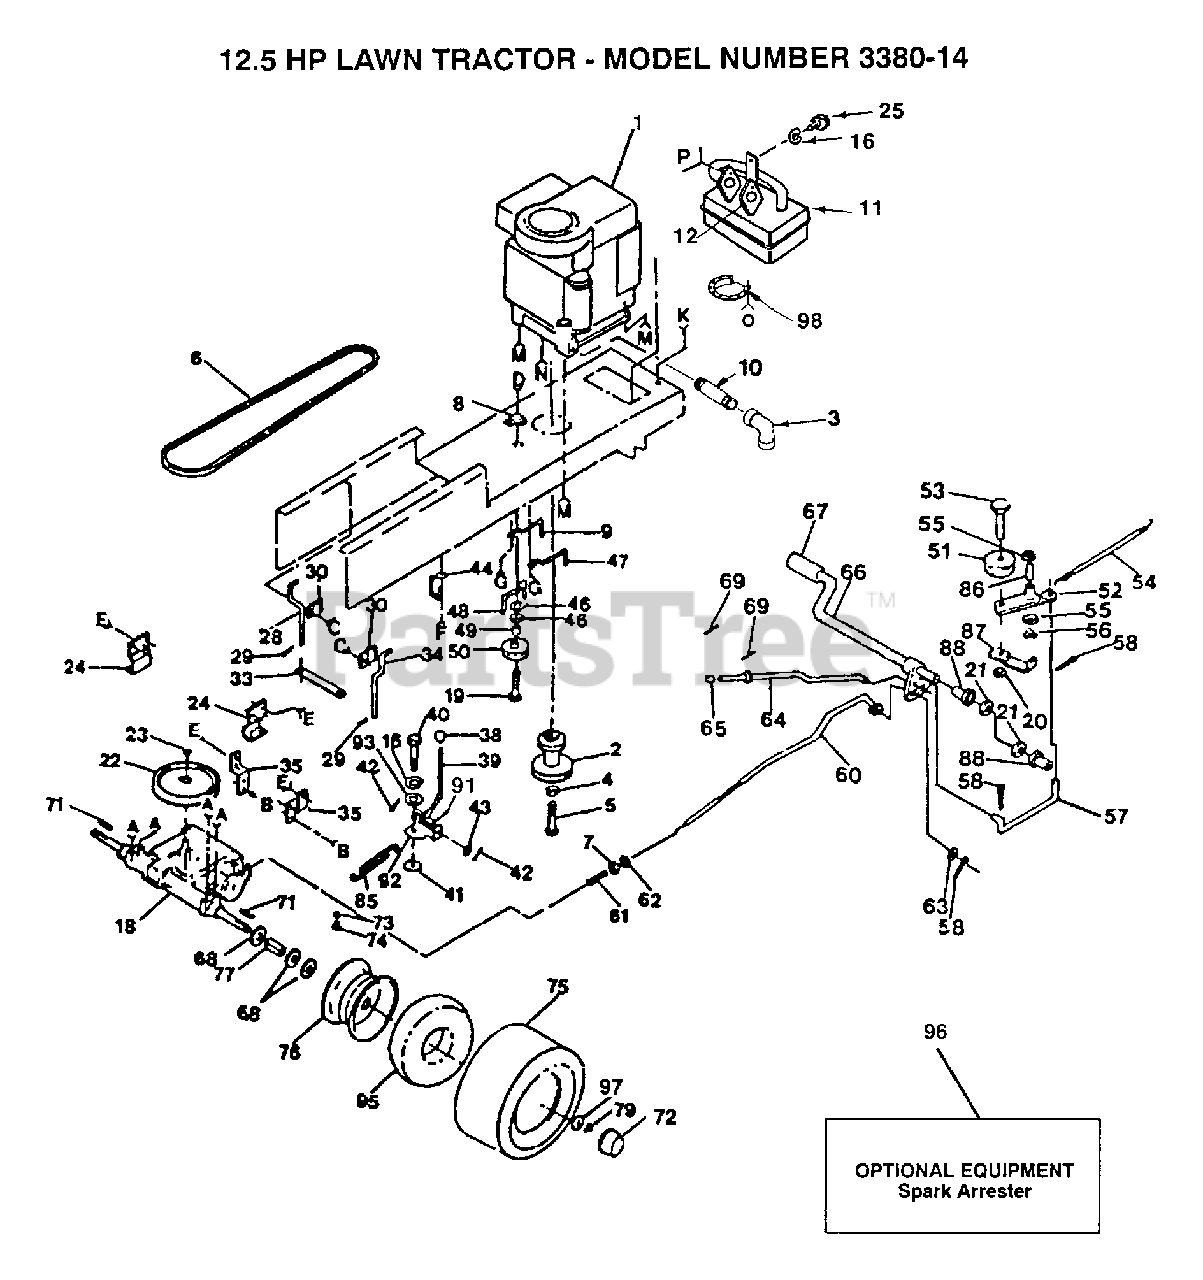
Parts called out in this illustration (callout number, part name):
3	ELBOW
4	LOCKWASHER
5	BOLT
6	BELT-V.90.0.GD.DR
7	NUT
8	CLIP T
9	KEEPER BELT ENGLH
10	PIPE NIPPLE
11	MUFFLER LT
16	LOCKWASHER
19	BOLT
21	WASHER LT
22	PULLEY TRANS
24	BRACKET LT
25	BOLT
28	KEEPER BELT LH
29	SPRING.RETAINER
30	CLAMP LT
33	STRAP LOCATOR
34	KEEPER BELTRH
35	STRAP TORQUE
38	KNOB T (1/2-HOLE)
39	ROD SHIFTER
41	WASH-SHFT PLT LT
42	PIN COTTER 1/8
43	WASHER
46	WASHER
47	"KEEPER,BLT ENG LT"
48	BELT KEEPER LT
49	SPACER T
50	PULLEY.IDLER.FLAT
52	ARM IDLER
54	"SPRING, RETURN LT"
55	WASHER LT
56	KLIP RING
57	"LINK, CLUTCH T"
58	COTTER PIN
60	BRAKE ROD LT
61	SPRING ROD LT
62	NUT
63	WASHER
65	PLUNGER CAP T
67	PEDAL COVER T
68	WASHER
71	SQUARE KEY
72	HUB CAP
73	VALVE CAP
74	VALVE STEM LT
77	SPACER LT
79	E-RING LT
86	"LY, BEARING"
87	RETAIN BELT
88	NYLON BEARING
91	SPRING LT
92	PLATE SHIFT LT
93	WASHER LT
95	TUBE.18X9.5-8
96	SPARK ARREST KIT
97	WASHER
98	DEFLECTOR.222573
